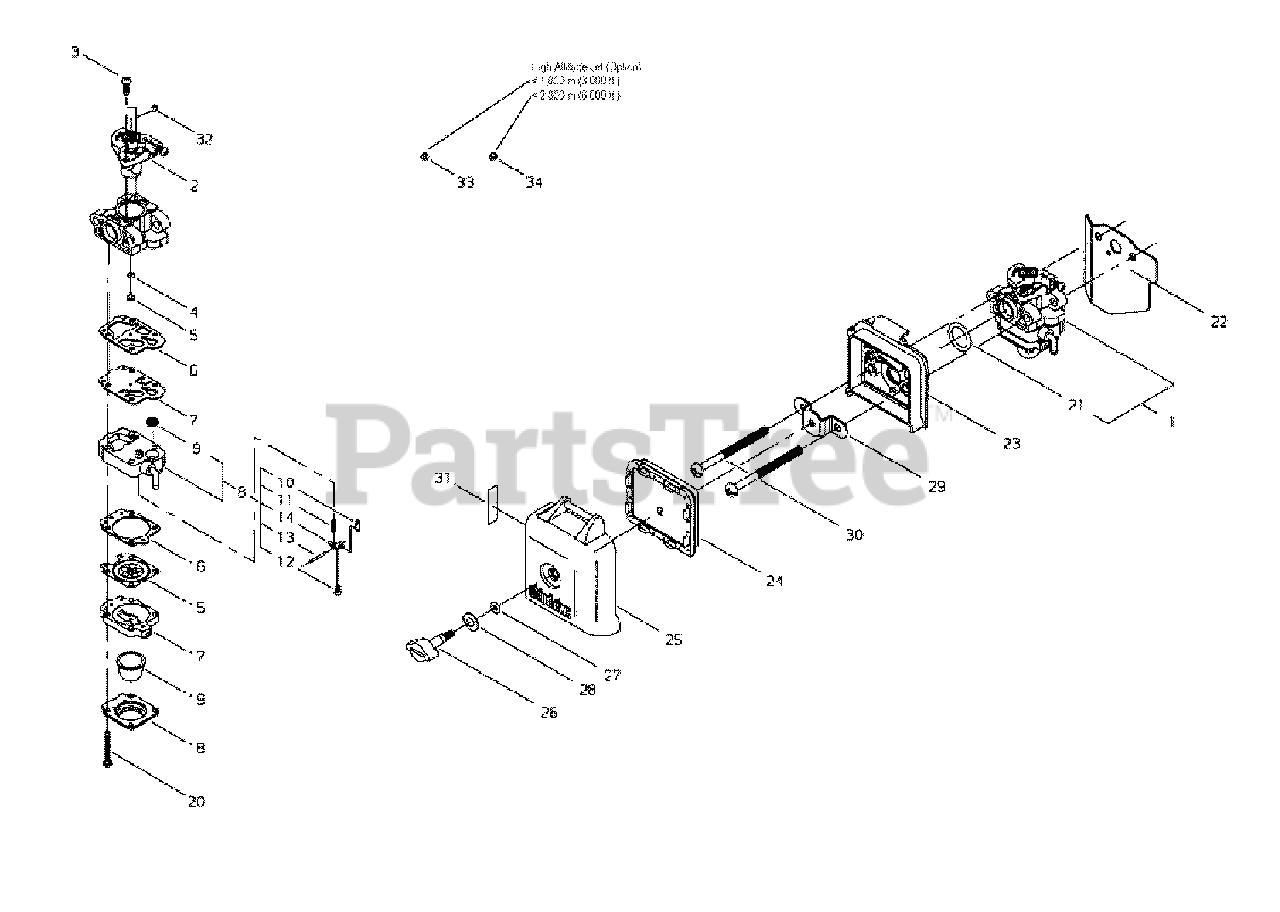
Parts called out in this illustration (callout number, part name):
1	CARBURETOR
2	VALVE ASSY, THROTTLE
3	SCREW, THROTTLE COLLAR
4	O-RING
5	JET, MAIN
6	GASKET, PUMP
7	DIAPHRAGM, PUMP
8	BODY ASSY, PUMP
9	SCREEN, FUEL INLET
10	VALVE, INLET NEEDLE
11	SPRING, METERING LEVER
12	SCREW
13	PIN, METERING LEVER
14	LEVER, METERING
15	DIAPHRAGM, METERING
16	GASKET, METERING DIAPHRAGM
17	BODY ASSY, PURGE
18	RETAINER, PURGE BULB
19	BULB, PURGE
20	SCREW
21	O-RING 15
22	GASKET, CARBURETOR
23	CASE, AIR FILTER
24	FILTER, AIR
25	COVER, AIR FILTER
26	THUMBSCREW
27	O-RING
28	WASHER, CONE M6
29	BRACKET
30	SCREW M5×60
31	LABEL, CHOKE
32	PLUG
33	JET, MAIN
34	JET, MAIN
